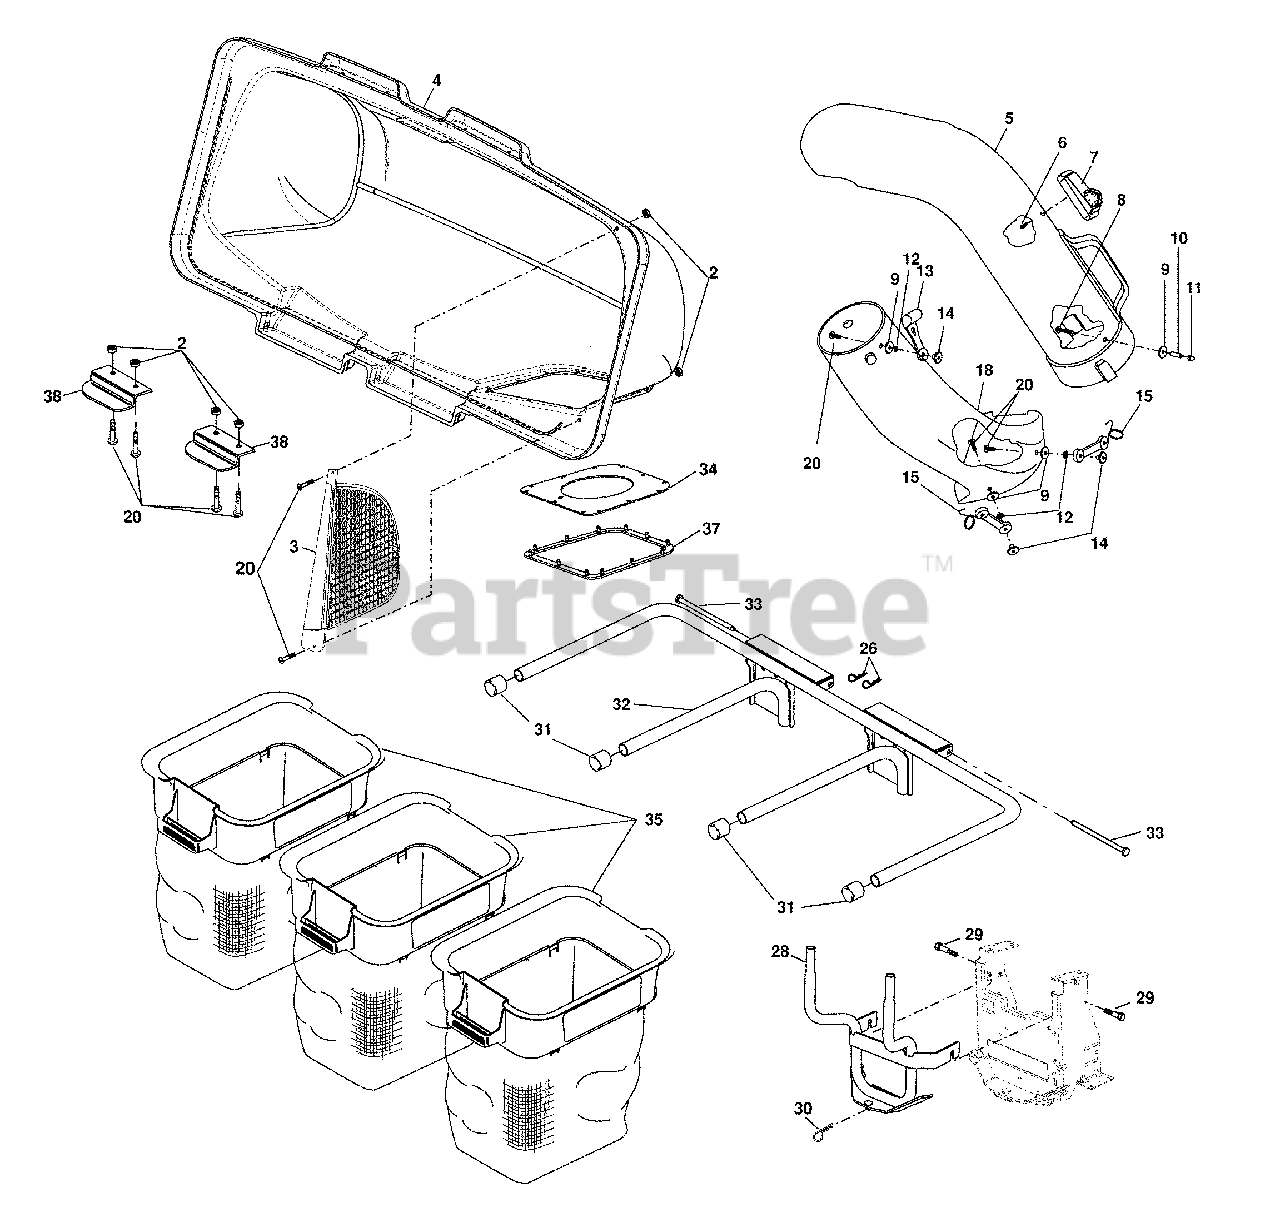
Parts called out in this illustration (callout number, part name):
2	Nut, Crown lock #10-24
3	Screen, Cover
4	Cover Assembly
5	Chute, Upper
6	Screw, Special #10-14x1/2
7	Full Bag Indicator
8	Screw, #10-24 x 1-1/8
9	Washer 3/16x3/4x16 Ga.
10	Spacer, Split
11	Nut, Acorn #10-24
12	Washer, lock
13	Latch, Chute
14	Nut, Weld
15	Latch, Hook
18	Chute, Lower
20	Screw #10-24 x 5/8
21	Spring, Cover L.H.
22	Spacer, Cover
23	Spring, Cover R.H.
24	Bracket, lock
25	Locknut
26	Spring, Retainer
28	Support Assembly
29	Shoulder bolt, self tapping
30	Spring, retainer
31	Plug, Tubing End
32	Bagger, Frame
33	Pin, Hinge
34	Gasket, Cover
38	Latch Handle, Cover
39	Strip, Reinforcement
